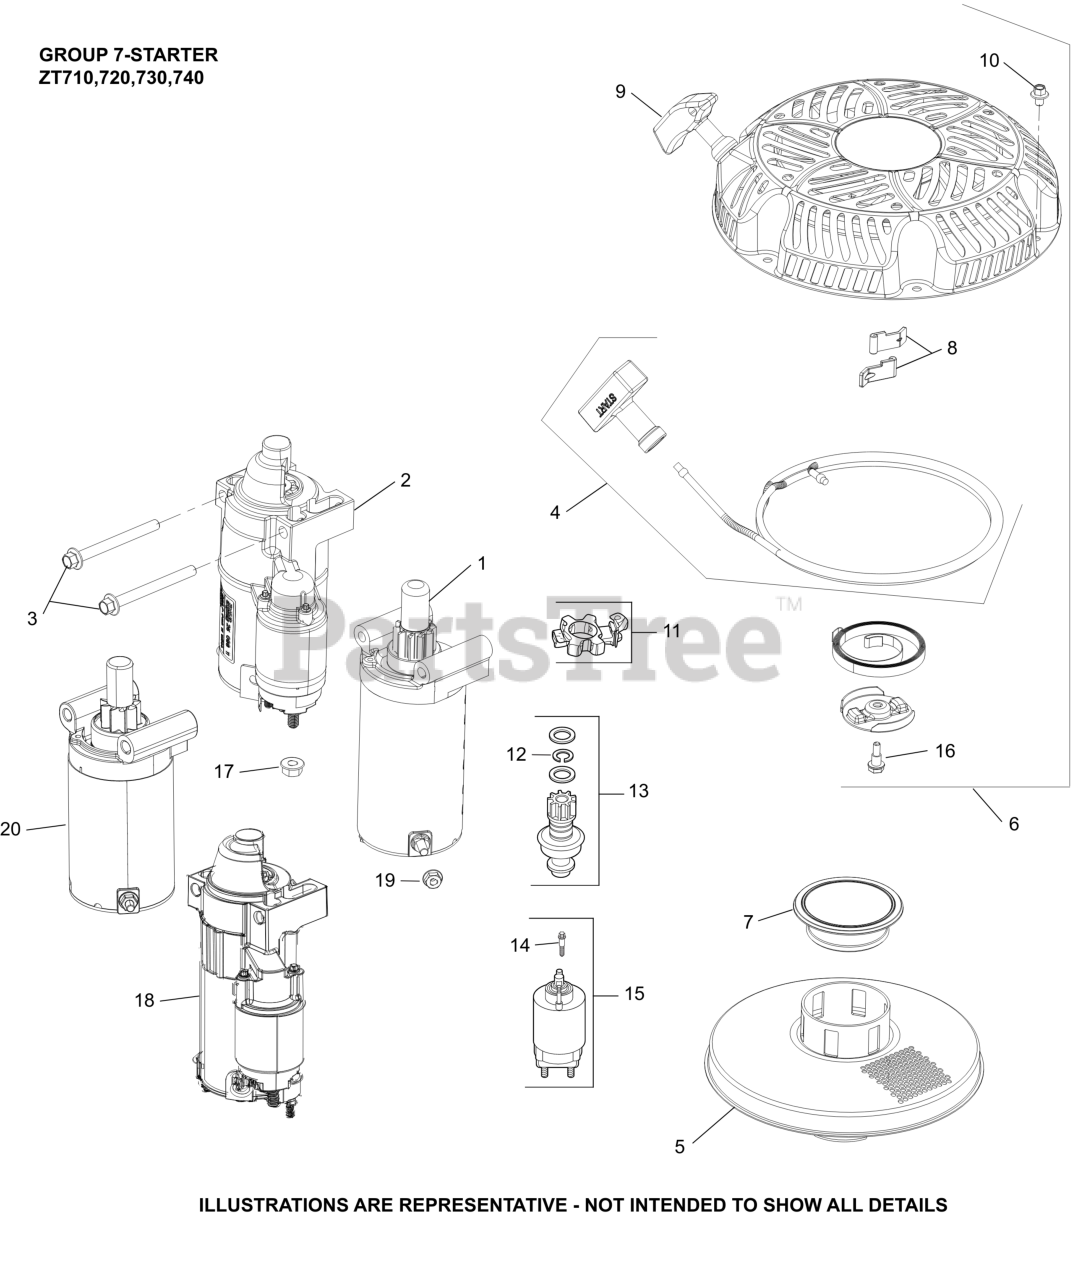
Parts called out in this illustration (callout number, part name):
2	STARTER, SOLENOID SHIFT (25 098 09-S)
3	SCREW, FLG M8X1.25X80
17	NUT, FLG M8X1.25
